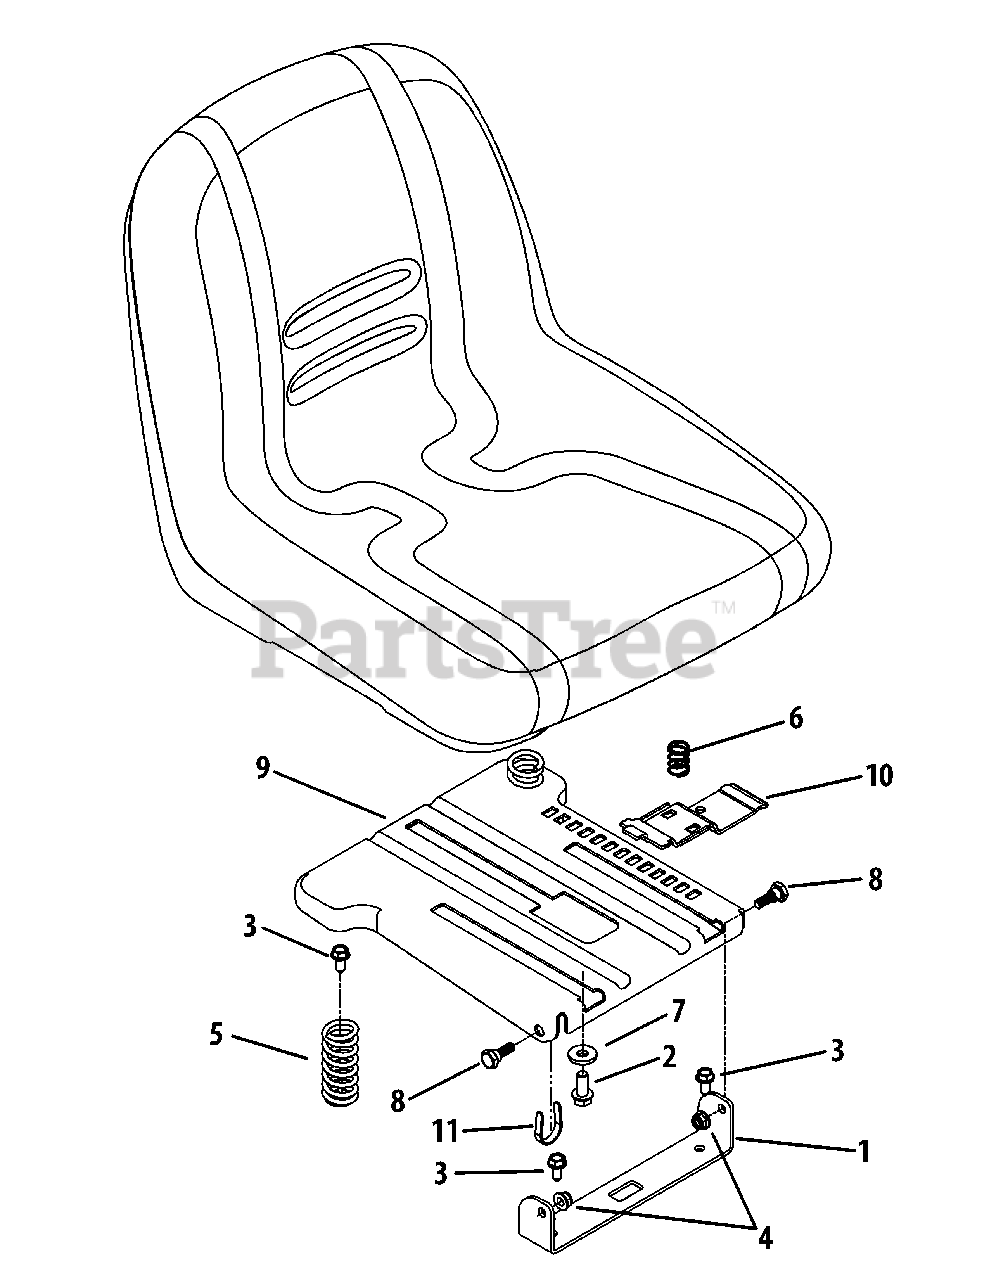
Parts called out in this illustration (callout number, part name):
1	Seat Bracket - Black
1	Seat Bracket - Red
2	Hex Flange Bolt, 3/8-16 x .875
3	Hex Washer Screw, 5/16-18 x .750
4	Flange Lock Nut, 5/16-18
5	Compression Spring
6	Compression Spring
7	Flat Washer, .385 x 1.0 x .135
8	Shoulder Screw, .437 x .268 x 5/16-18
9	Seat Mount Bracket - Black
9	Seat Mount Bracket - Red
10	Seat Adjustment Lever
